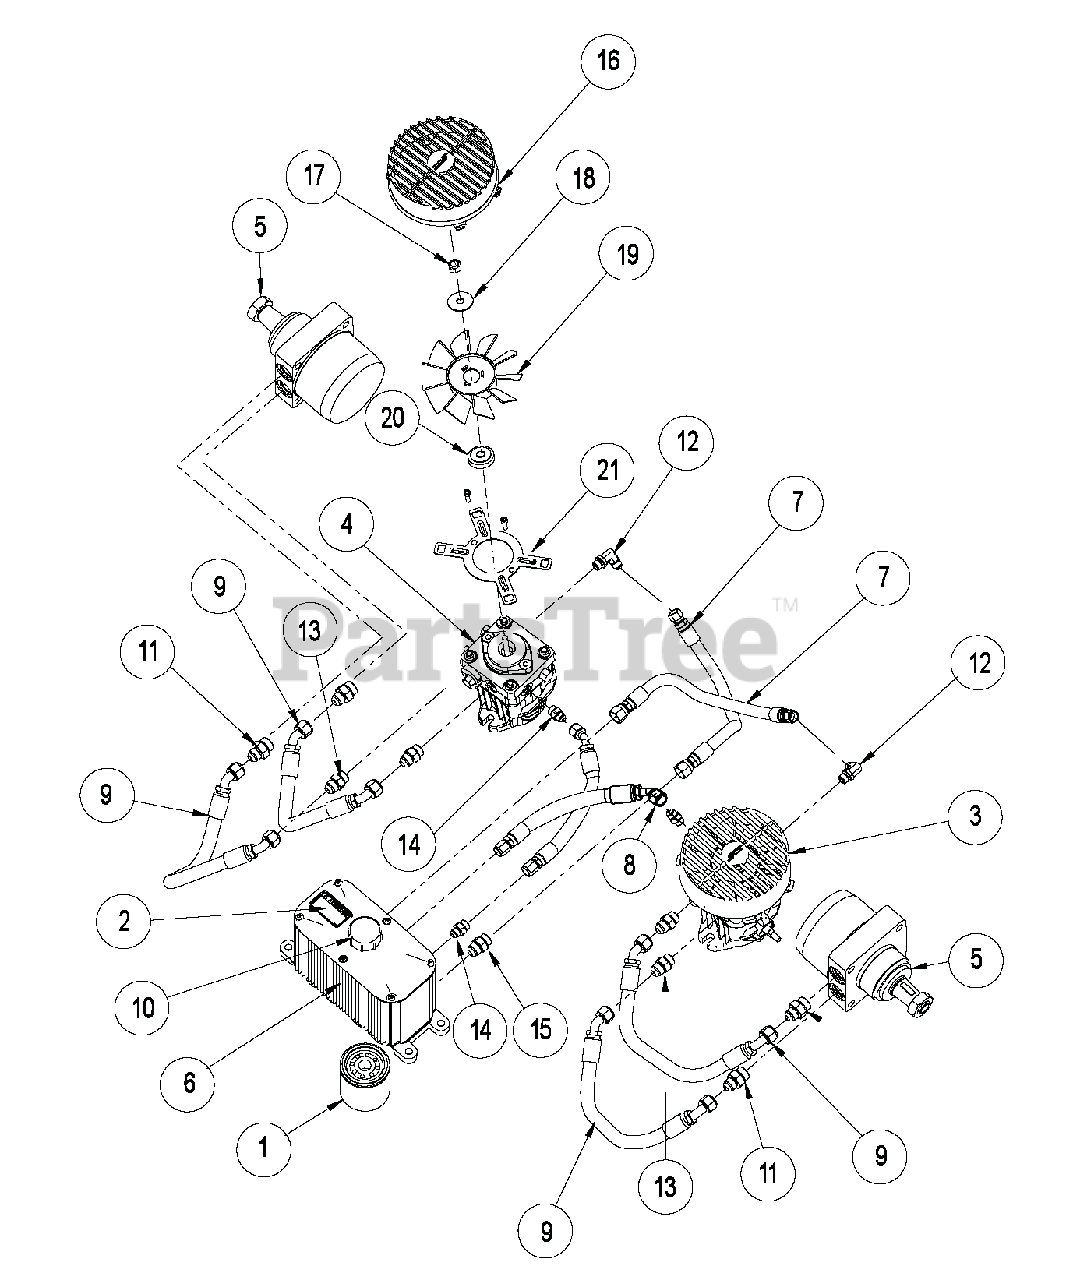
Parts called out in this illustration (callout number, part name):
1	FILTER, 25 MICRON
2	DECAL, ATTENTION HYD. RES.
3	PUMP, HYDRO LH
4	PUMP, HYDRO RH
5	PARKER TJ WHEEL MOTOR TL195
6	ASSY, HYD. TANK W/DECAL S/O
7	HOSE, HYD-6 -9FJIC -12FJIC 15
8	HOSE, HYD--6 -9FJIC45 7
9	HOSE, HYD-8 -12FJIC45 18
10	CAP, HYDRAULIC
11	FTG, ADP 3/4-16MJICX7/8-14MOR
12	FTG, 90 9/16 MOR X 9/16 MJIC
13	FTG, ADP 3/4-16MORX3/4-16MJIC
14	FTG, ADP 9/16MORX9/16MJIC
15	FTG, ADP 3/4-16MORX3/4-16MJIC
16	SHROUD, HG PUMP S/O
17	LOCKNUT, 3/8-24 CROWN Y
18	WASHER, .375X1.25X.072 BLVL U
19	FAN, HORNET PUMP S/O
20	HUB, BDP16 FAN
21	PLATE, FAN SHROUD MOUNT S/O
